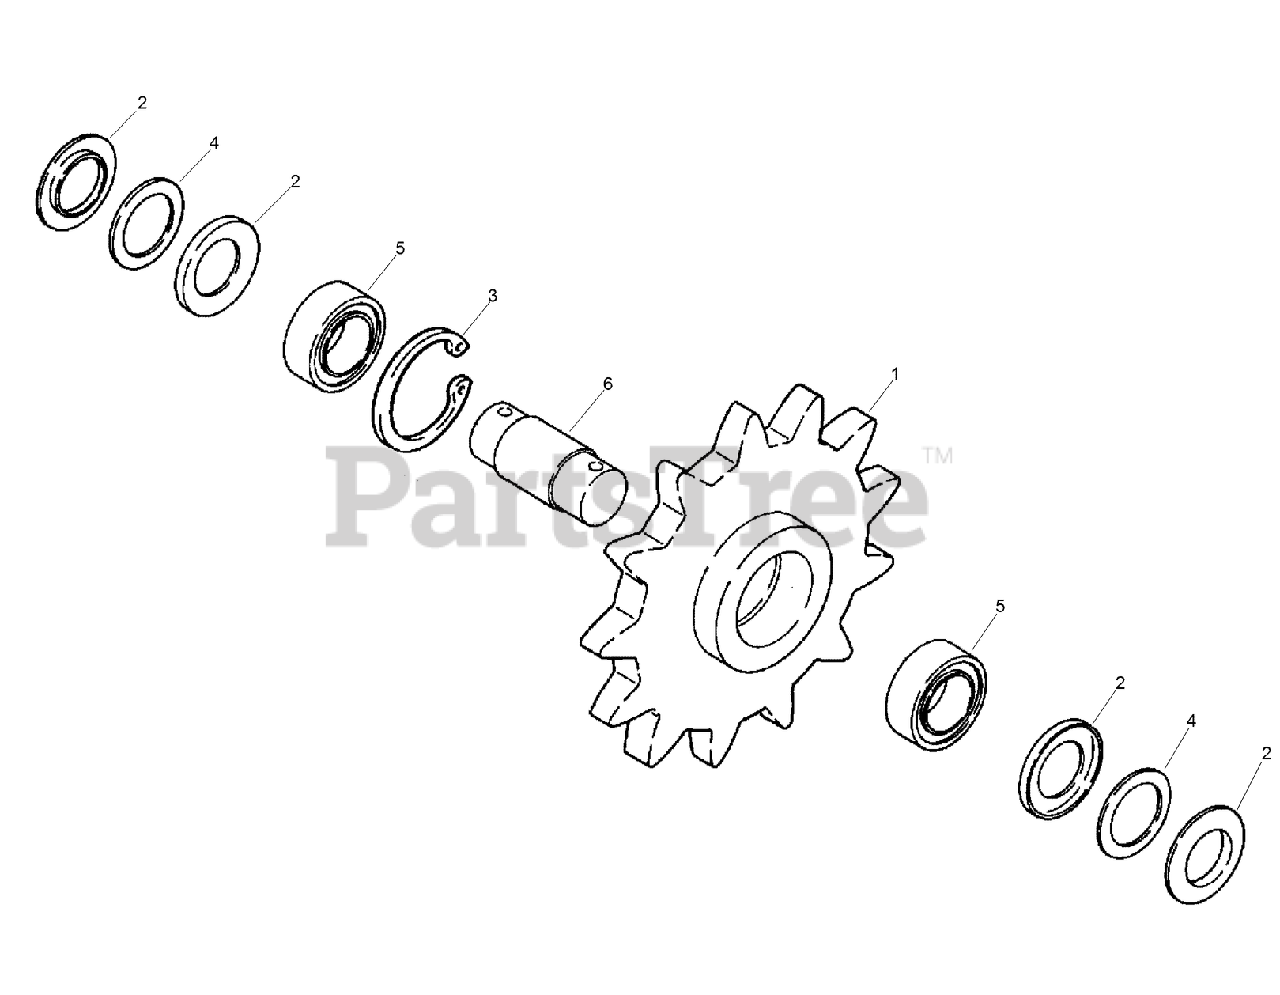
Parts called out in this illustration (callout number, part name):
1	SPROCKET - 311 Chain
1	SPROCKET - 408 Chain
3	RING - Retaining, # 393
4	WASHER - Special
5	BEARING - Ball, Idler Sprocket
6	SHAFT - Boom End Sprocket, Non-Lubricated
